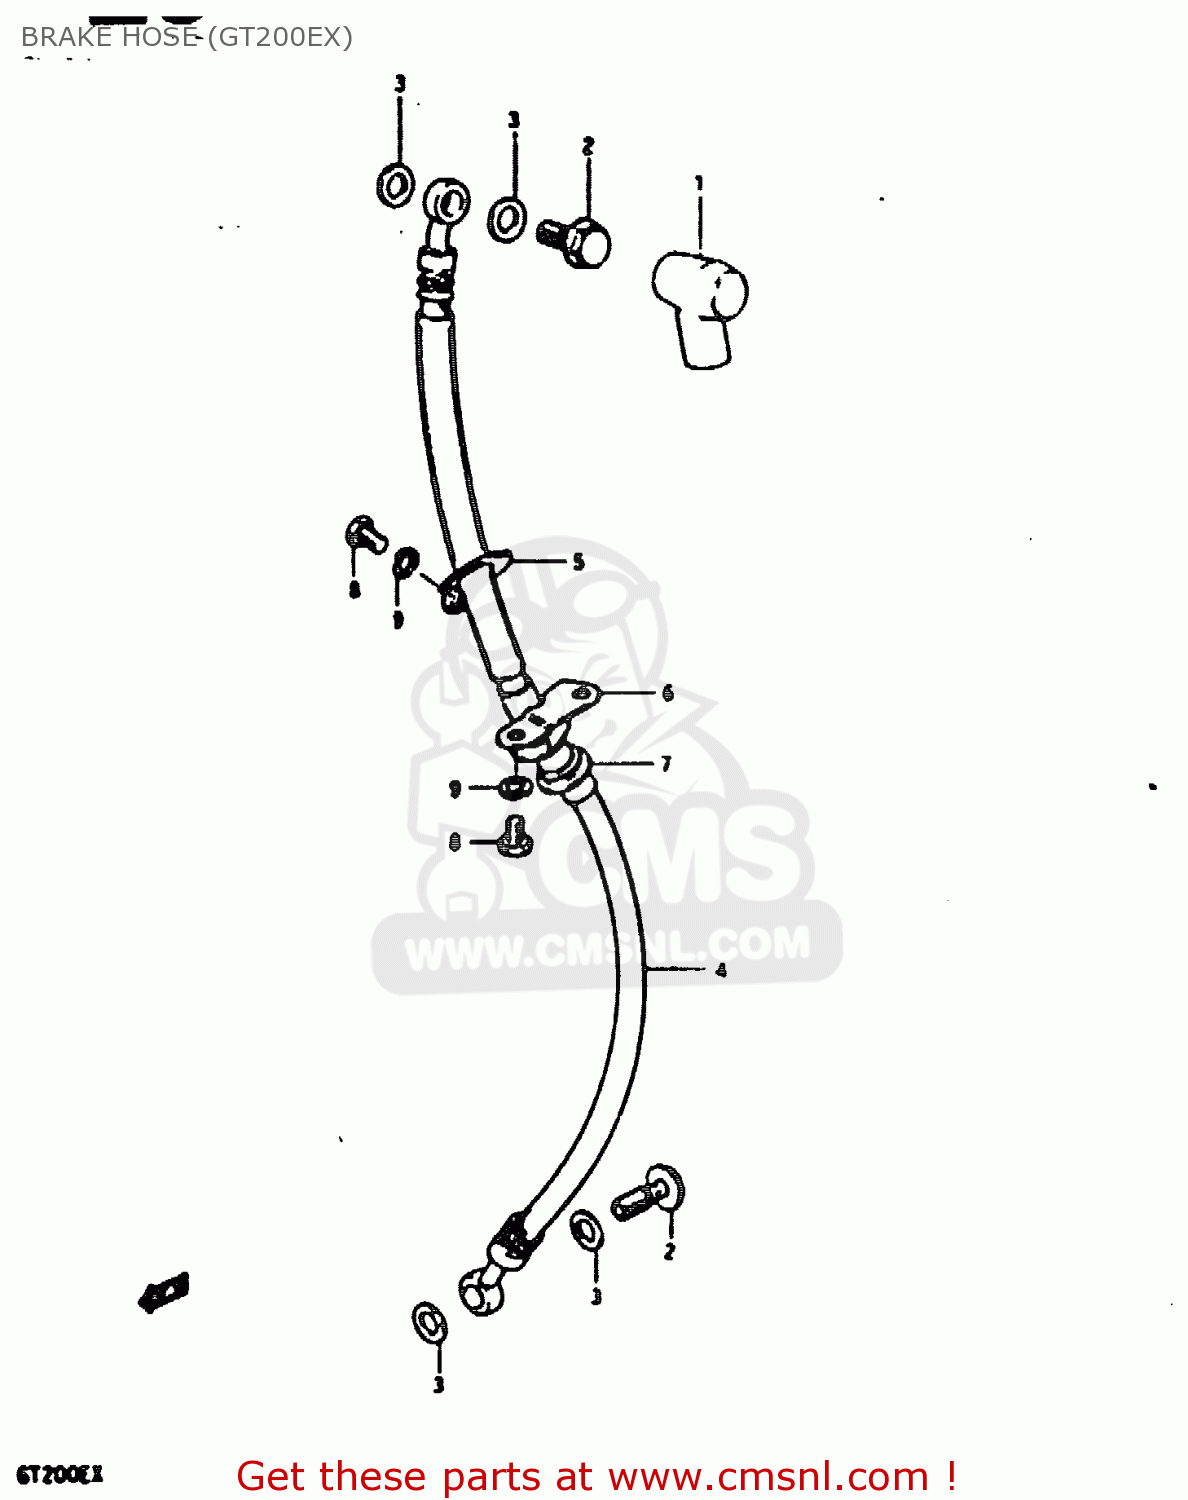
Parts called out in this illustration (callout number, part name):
1	BOOT,MASTER CYLINDER
2	BOLT,UNION
3	WASHER
4	HOSE, BRAKE (FLAT HANDLE)
5	GUIDE, HOSE NO.1
6	GUIDE,BRAKE HOSE
7	GROMMET,BRAKE HOSE GUIDE
8	BOLT
9	LOCK WASHER
